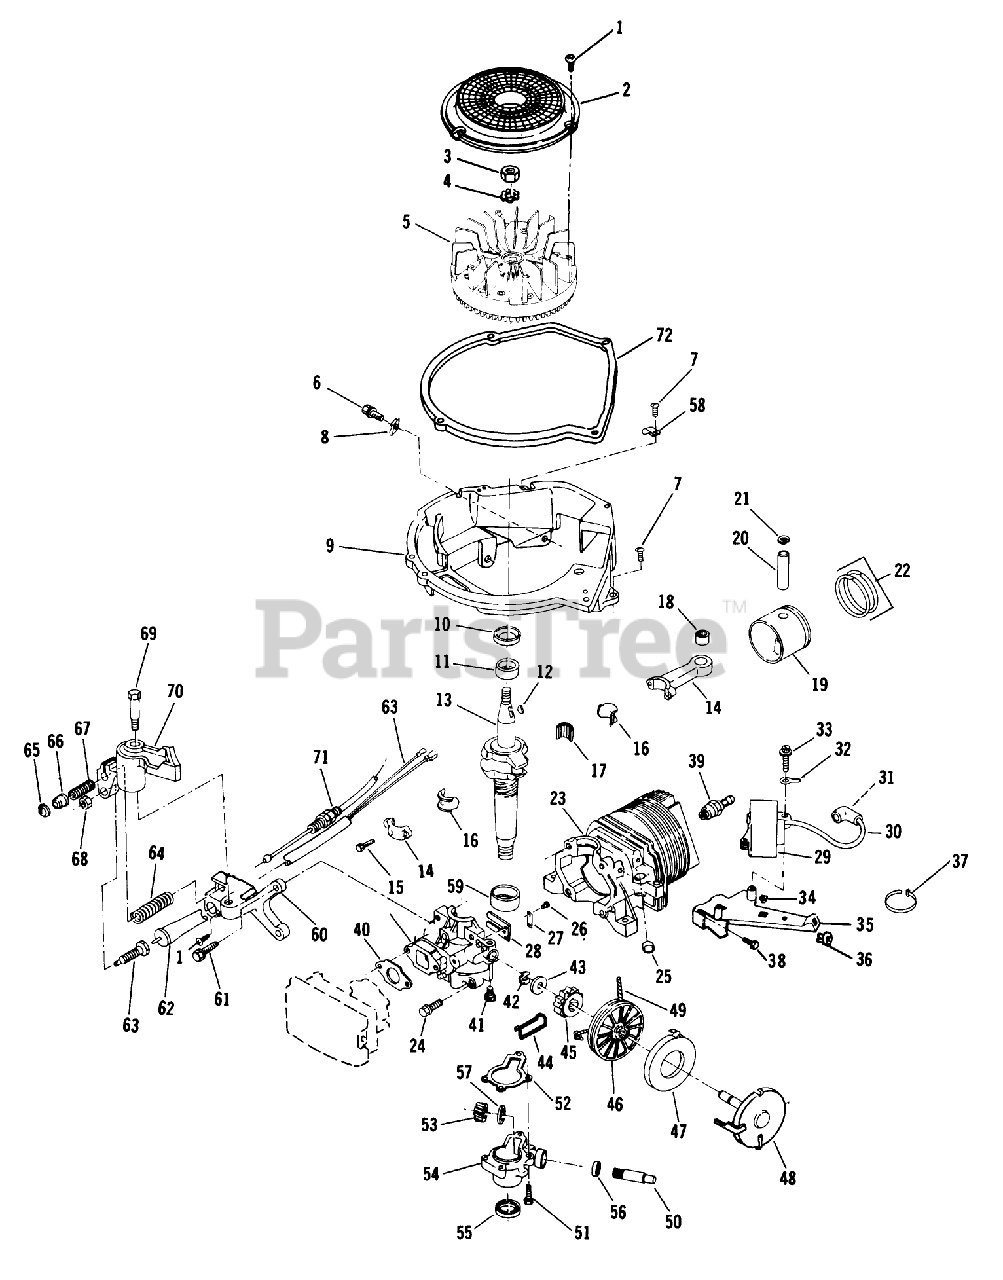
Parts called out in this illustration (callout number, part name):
1	SCREW F
3	NUT
6	SCREW-SEMS
7	SCREW F
11	BEARING V
12	KEY
15	SCREW-HSH
16	LINER ASM
18	BEARING AY F
22	RING-RETAINING
24	SCREW S
25	PLUG-CORE VF
27	PLATE-BACKUP, REED
30	HT LEAD&COVER XEV
32	TERMINAL S
34	NUT-CLIP
36	NUT-CLIP
40	GASKET CARB S
43	WASHER S
46	PULLEY STARTER S
47	SPRING&RET.AY S
48	SPRING CUP&PIN S
49	ROPE-STARTER
52	GASKET S
53	GEAR, DR SHAFT S
55	SEAL-OIL
56	SEAL S
57	THRUST WASHER
59	BEARING S
60	BRACKET-BRAKE F
63	PLUNGER S
64	SPRING-BRAKE
65	RETAINER S
66	ACTUATOR-LEVER, BRAKE
67	SPRING
71	CONTROL CABLE
